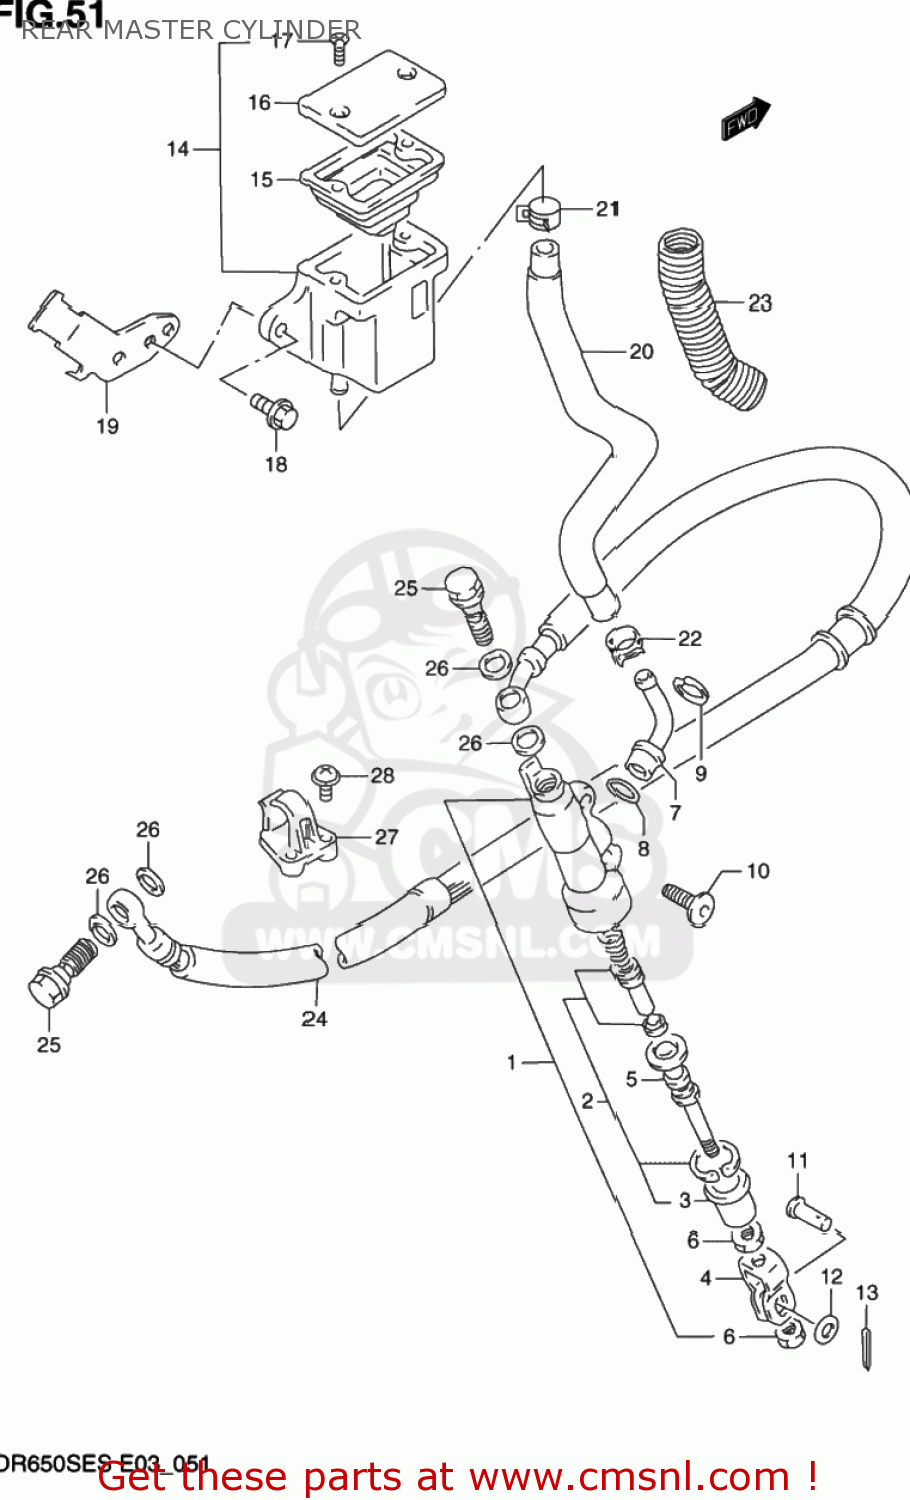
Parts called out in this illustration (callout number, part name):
1	CYLINDER ASSY,RR MASTER
2	PISTON/CUP SET
3	BOOT
4	YOKE
5	ROD,PUSH
6	NUT
7	CONNECTOR
8	O RING
9	CIRCLIP
10	BOLT(6X18)
11	PIN
12	WASHER
13	PIN
14	TANK ASSY,RESERVOIR
15	DIAPHRAGM
16	CAP
17	SCREW
18	BOLT
19	PLATE COMP,RESERVOIR T
20	HOSE COMP,RESERVOIR TANK
21	CLIP
22	CLIP
23	SHIELD,RESERVOIR TANK HOSE
24	HOSE COMP,REAR BRAKE
25	BOLT UNION
26	WASHER(10X15X1.5)
27	GUIDE,RR BRAKE HOSE
28	SCREW
